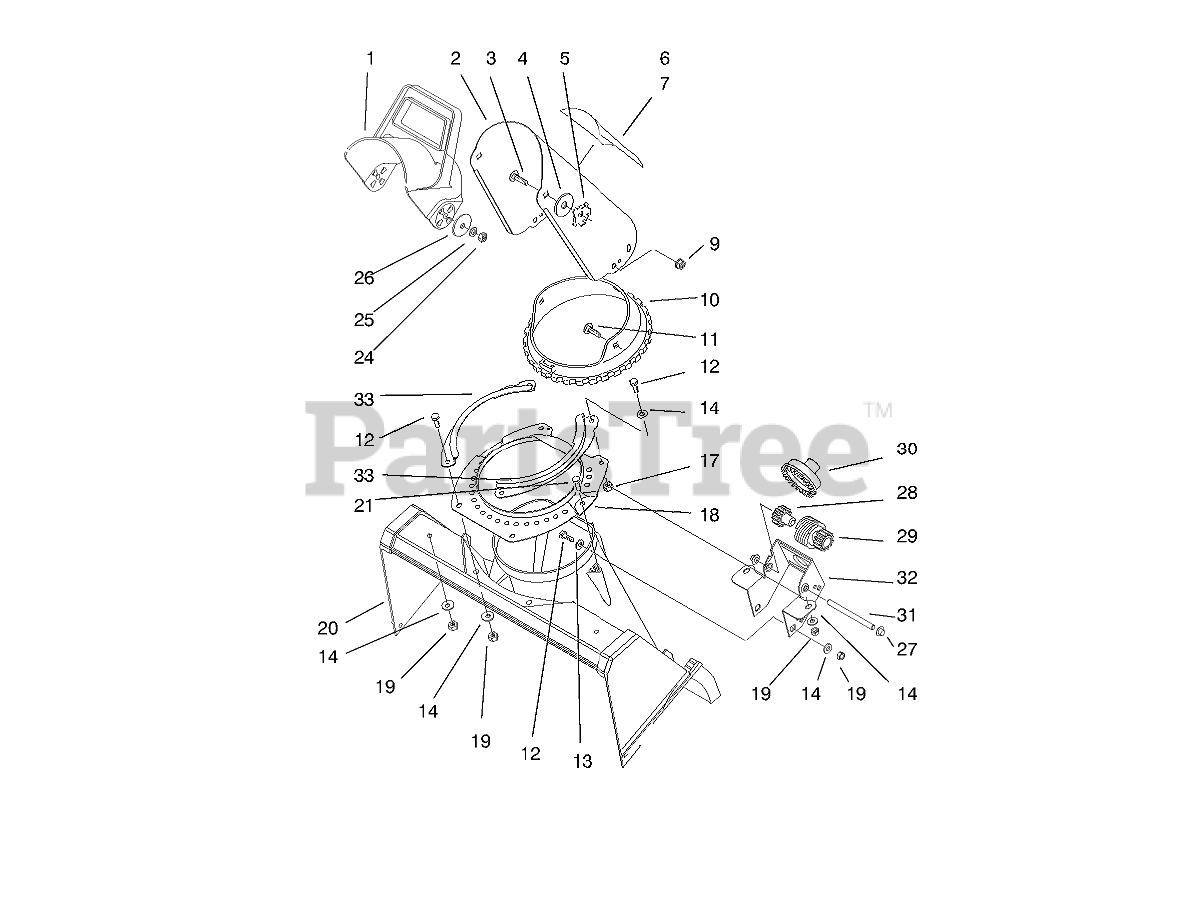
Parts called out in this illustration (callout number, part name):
1	CHUTE-DEFLECTOR
2	Chute-Discharge
2	CHUTE ASM W/DECAL
2	CHUTE ASM
3	SCREW-CARR
4	WASHER-RUBBER
5	PLATE-FRICTION
6	DECAL - DANGER DISCHARGE
7	DECAL-DANGER
9	NUT-KEPS
10	RING-GEAR, CHUTE
11	SCREW-CARR
12	SCREW-HH
14	WASHER-FLAT
18	Ring-Chute Support
19	NUT-LOCK, NI
20	HOUSING
21	SCREW-PLASTITE
24	NUT-LOCK, NI
25	WASHER-BELLEVILLE
26	WASHER-FLAT
27	NUT-PUSH
28	GEAR-SPUR, SPACER
29	GEAR-SPUR/WORM
30	GEAR-FACE
31	SHAFT-GEAR, WORM
32	Bracket-Chute Gear
33	Retainer-Chute Ring
